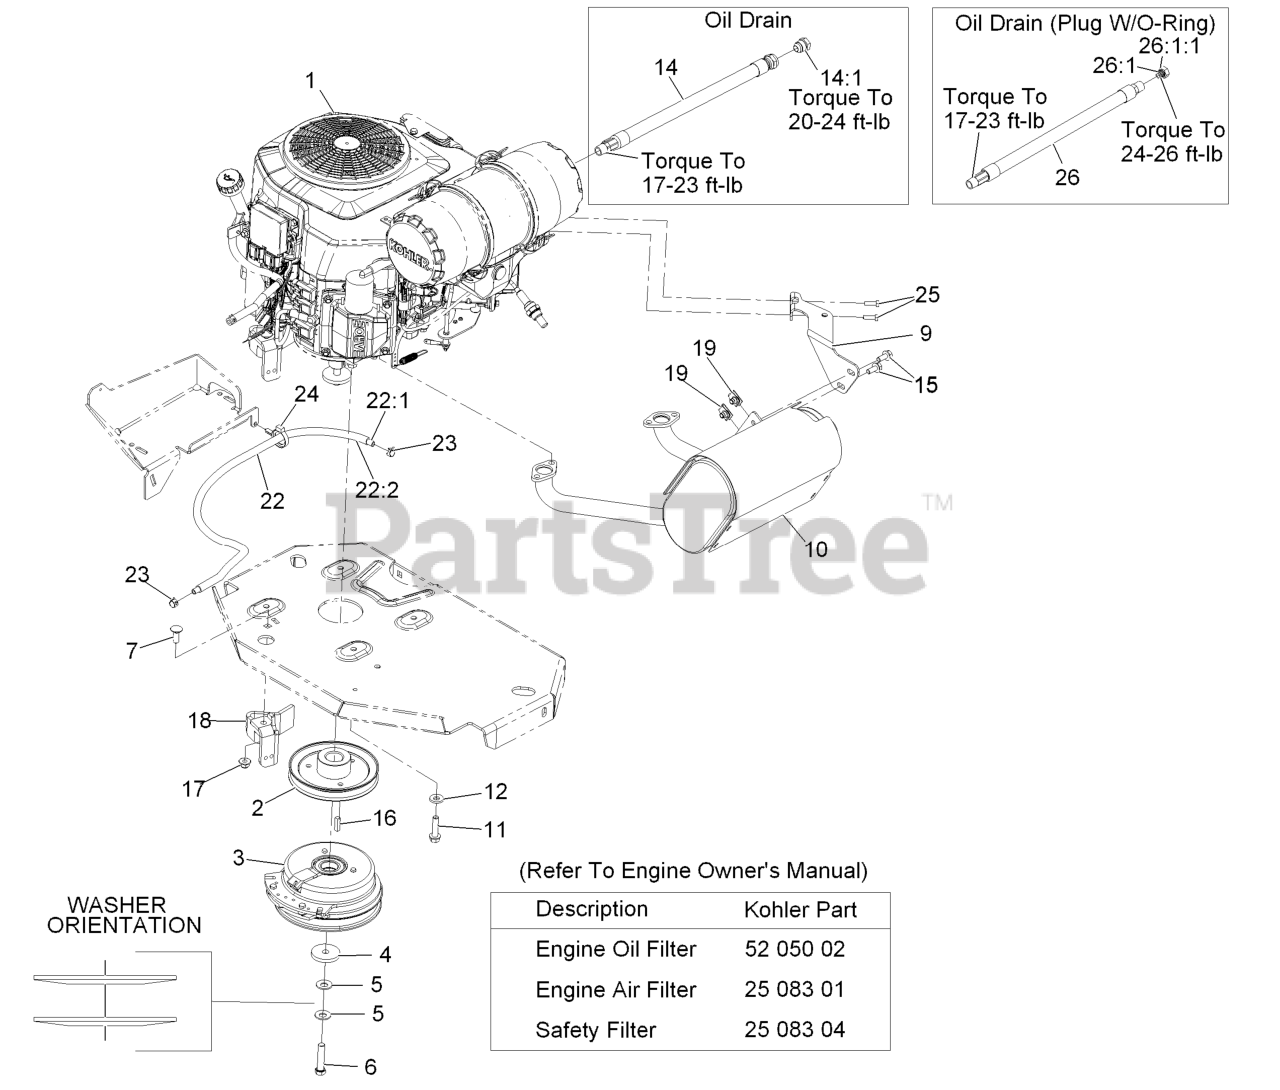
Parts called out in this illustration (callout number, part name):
1	Engine,Koh 29hp Efi
2	SHEAVE
3	CLUTCH KIT
4	WASHER-CLUTCH
5	WASHER-SPRING
6	SCREW-HH W/LOCTITE
7	SCREW-CARR
9	MUFFLER BRACKET KIT
11	SCREW-HWH
12	WASHER-BELLEVILLE
15	SCREW-HHF
17	NUT-HF, NI
18	CLUTCH-ANCHOR
22	FUEL LINE ASM
22:1	HOSE-FUEL
22:2	SLEEVE-THERMAL
23	CLAMP-HOSE
24	CLAMP-HOSE
25	SCREW-HH M6-1 X 20Mm W/Patch
26	OIL DRAIN HOSE ASM
26:1	PLUG-HH
26:1:1	O-RING
